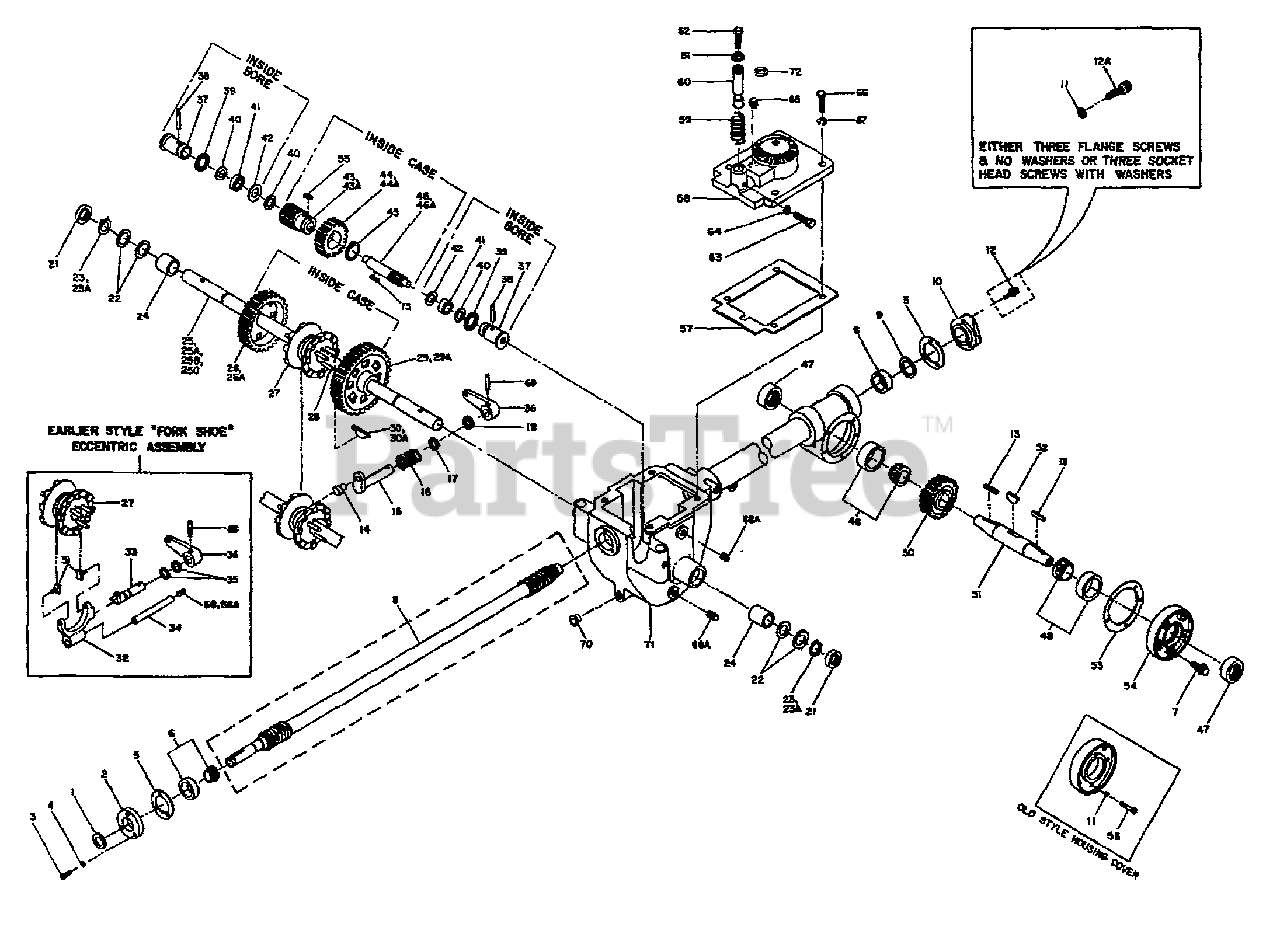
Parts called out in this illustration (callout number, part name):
1	SEAL-PINION SHAFT PT/85030/00
2	COVER-FRONT
3	SCR-HH 1/4-20X.75 G5 ZP
4	WASHER-LK .25 ZP
5	GASKET-BRG COVER
6	KIT-BRG CONE&RACE-DRIVESHAFT
7	SCR-HH 1/4-20X.625
8	KIT-DRIVESHAFT HORSE
9	SHIM-1.75X1.5X.01
9	SHIM-1.75X1.5X.03
9	SHIM-1.75X1.5X.005
10	CAP-REAR #1115
11	WASHER-LK .25 HI-COLLAR
12	SCR-HFLK 1/4-20X.875
12A	SCR-HXSKT 1/4-20X1.0
13	KEY-.188 SQX1.0
14	PIN-.375 X .72
15	SHAFT-ECCENTRIC HORSE TLR
16	SPRING .845 X 1.25
17	WASHER # .875 X .65 X .06
18	SEAL-OIL ECCENTRIC
19	WASHER-LK .25 HI-COLLAR
21	SEAL-OIL WHEELSHAFT
22	SHIM-1.375X1.015X.062
22	SHIM-1.375X1.015X.03
22	SHIM-1.375X1.015X.015
22	SHIM-1.375X1.015X.01
22	SHIM-1.375X1.015X.005
23	RING-HEAVY EXT .906 ID
23A	RING-RETAINING 5100-100
24	BUSHING-1.25X1.005X1.5
25	KIT-WHEELSHAFT
25A	KIT-WHEELSHAFT
25B	KIT-WHEELSHAFT
25C	KIT-WHEELSHAFT
26	GEAR-SPUR 46 TEETH MACH
26A	GEAR-SPUR-50 TEETH-MACH
27	CLUTCH-MACH
28	PIN-CLUTCH .25 2.65
29	GEAR-SPUR 56 TEETH MACH
29A	GEAR-SPUR 60 TEETH-MACH
30	KEY-HI PRO .25X1.812
30A	KEY-HI PRO .25X1.062
31	PIN-.375 X .72
32	CLUTCH FORK
33	SHAFT-ECC WITH O RING
34	PIN-.5X4.0 FORK #
35	RING-O .625 X .438
36	LEVER-ECC. #1029
37	PLUG-PINION BRG W/RING
38	PIN-SPIROL .25 X 2.0
39	RING-O 1 ID
40	SHIM-1.234X1.015X.033
40	SHIM-1.234X1.015X.062
40	SHIM-1.234X1.015X.01
41	BRG-BALL (7 BALLS)
42	WASHER-# 1X.484X.06
43	GEAR-SPUR 20 TEETH MACH
43A	GEAR-SPLINE-16 TEETH-MACH
44	GEAR-WORM 36 TEETH MACH
44A	GEAR-WORM-30 TEETH-MACH
45	RING-RETAINING 5100-150
46	GEAR-SPLINE 10 TEETH MACH
46A	GEAR-SPLINE 6 TEETH MACHINE
47	SEAL-OIL TILLERSHAFT
48	TAPERED, BEARING & CUP
50	WORM GEAR
50A	KIT-TILLER GEAR & BRGS
51	SHAFT-TILLER W/KEY
52	KEY-WOODRUFF .25X1.12
53	GASKET-TILLER COVER
54	COVER-W/SCRS(TLR) (9780)
55	KEY
56	SCR-HXSKT 1/4-20X.625
57	GASKET-TRANS COVER
58	ASSM-COVER W/BOLT-HORSE
59	SPRING .78 X 2.125
59A	SPRING-REV PLUNGER ZP
60	ASSM-NEUTRAL PLUNGER
61	NUT-HFLK 3/8-16 ZP
62	BOLT-HH 3/8-16X1.5 FTH ZP
63	SCR-HH 5/16-18X1.0 G5 ZP
64	NUT-HEX 5/16-18 ZP
65	PLUG-PIPE 3/8 NPT
66	BOLT-HH 3/8-16X1.5 FTH ZP
67	WASHER-LK .375 @ DEPL
68	PLUG-PIPE 3/8 NPT
68A	PLUG-PIPE 1/4 NPT
69	PIN-SPIROL .188 X 1.25
70	PLUG-CAP (RED)
71	TRANSMISSION CASE, HOUSING & TUBE ASSEMBLY
72	RING-KLIP EXT .594 ID ZP
